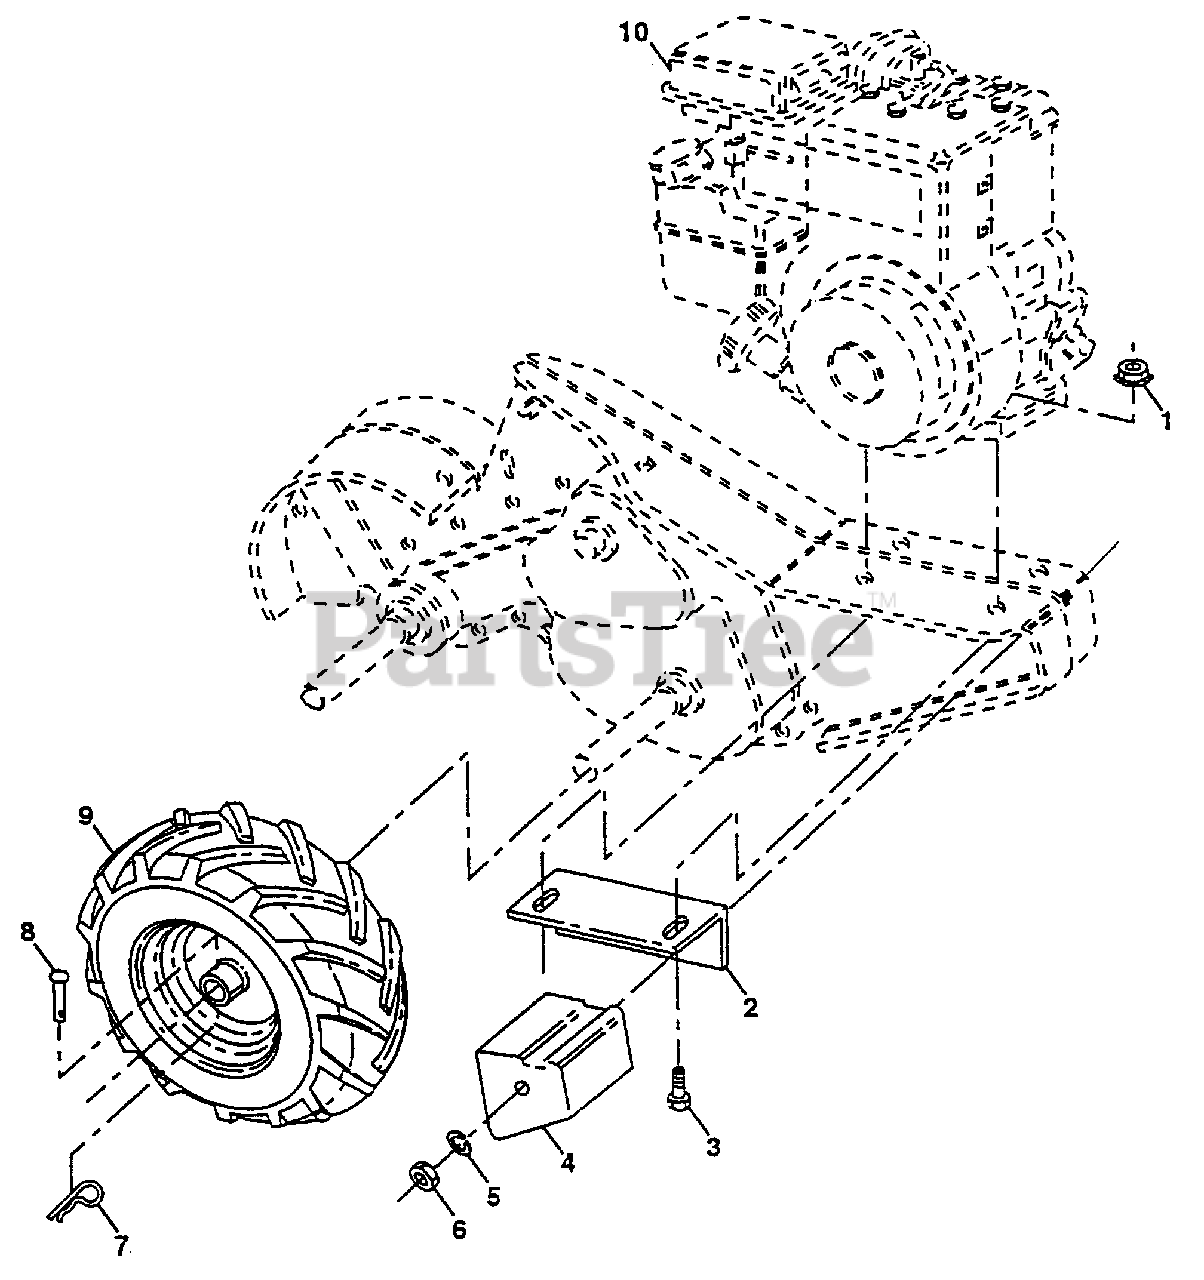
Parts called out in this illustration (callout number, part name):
1	Nut, Keps 5/16-18
2	Bracket, Reinforcment
3	Bolt, Hex 5/16-18 x 1-1/2
4	Counter Weight, R.H.
5	Washer, Lock 3/8
6	Nut, Hex 3/8-16
7	Clip, Hairpin
8	Rivet, Drilled
9	Tire Valve
